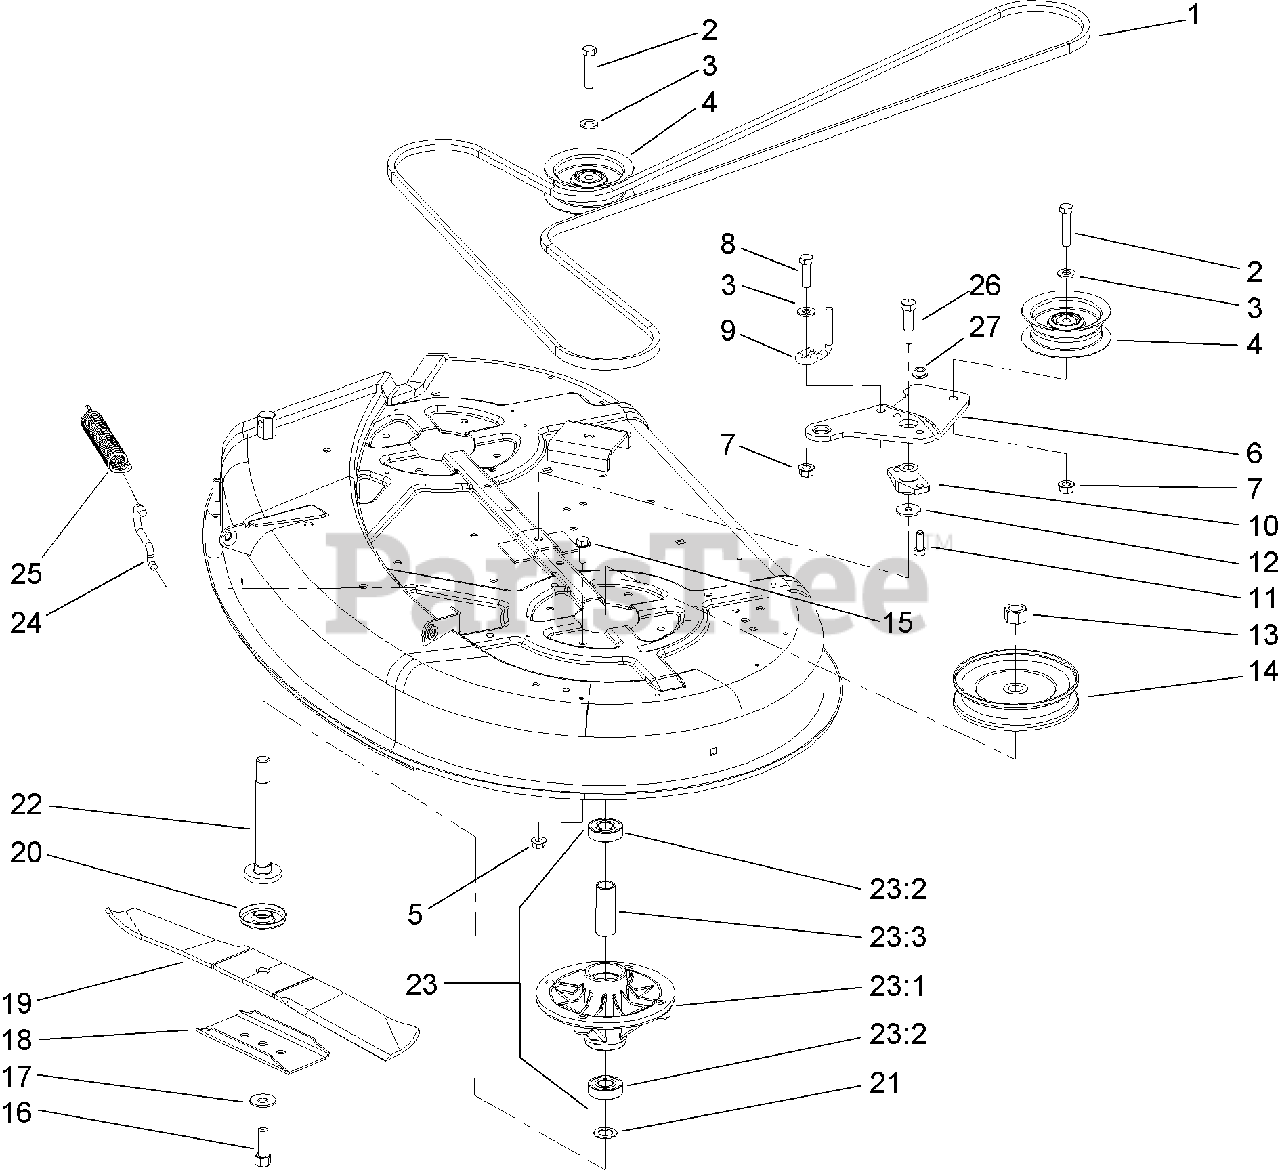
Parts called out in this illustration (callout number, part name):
2	SCREW-HH
3	WASHER-FLAT
4	PULLEY-IDLER, FLAT
8	SCREW-HH
9	GUIDE-IDLER, BELT
10	BUSHING-ARM, IDLER
11	SCREW-HH
12	WASHER-PIVOT
13	NUT-HEX
14	PULLY-DECK
15	SCREW-TAPTITE
16	SCREW-BLADE
17	WASHER-BELLEVILLE
18	STIFFENER-BLADE
20	SHIELD-BEARING
22	SHAFT-SPINDLE
23	Spindle ASM
23:1	HOUSING-SPINDLE
23:2	BEARING-BALL
23:3	SPACER-BEARING
24	HOOK-RETURN, SPRING
25	SPRING-EXTENSION
26	BOLT-SHOULDER
27	NUT-LOCK, NI
